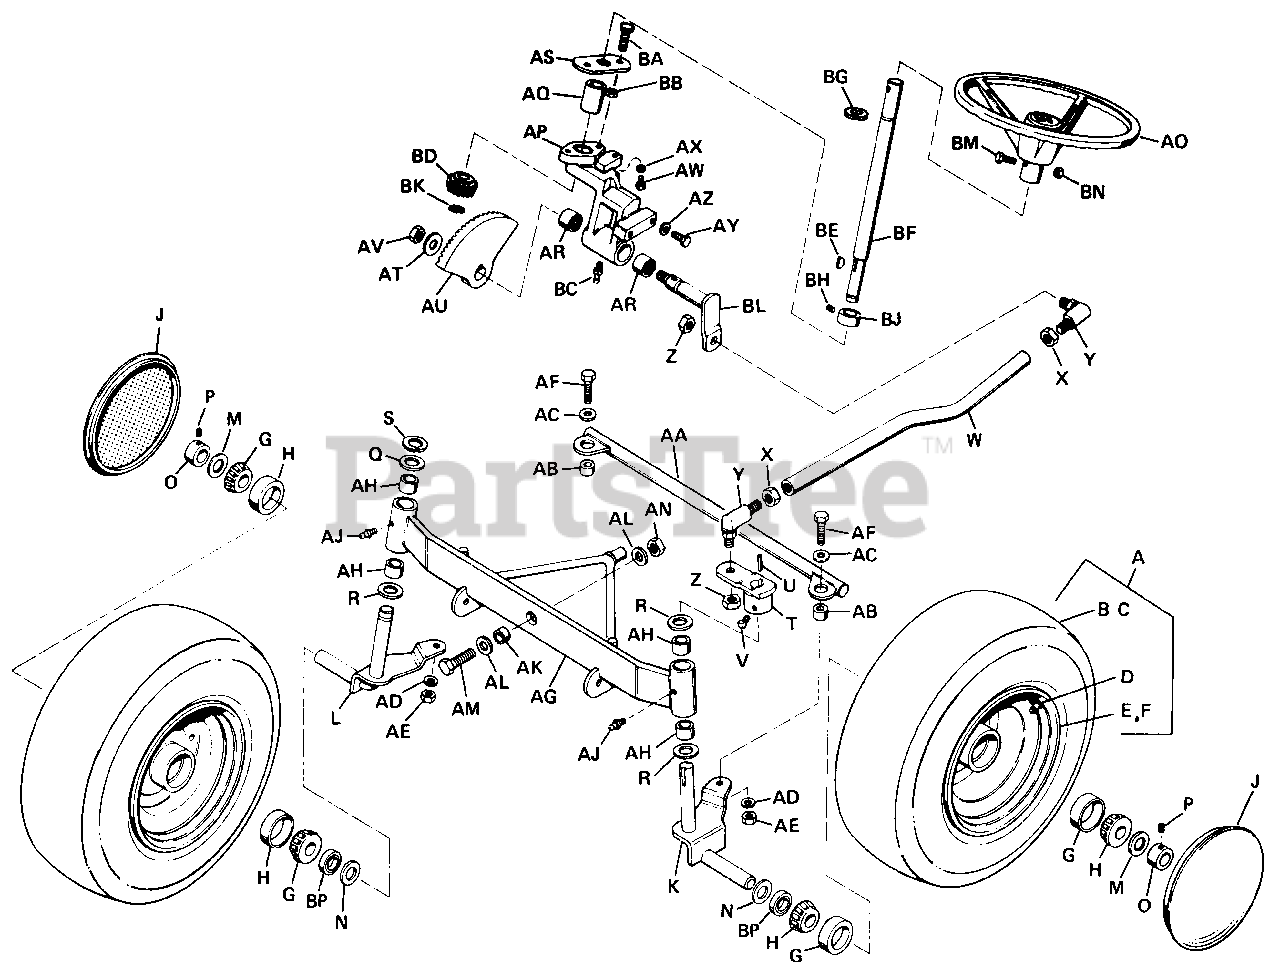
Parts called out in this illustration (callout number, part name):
A	Wheel & Tire Assy. (14 H.P.)
B	Tire (14 H.P.)
C	Tube (14 H.P.)
D	Valve Stem & Cap (14 H.P.)
E	Wheel-Sub Assy. (14 H.P.)
F	Wheel (Front) (14 H.P.)
G	Bearing, Cup
H	Bearing, Cone (Without Seal)
J	Hub Cap
K	Spindle Assy. L.H.
L	Spindle Assy. R.H.
O	Collar, Set
P	Cup Pt. Socket Head Set Screw, 5/16"-18 N.C. x 5/16"
Q	Washer (Use Beneath Snap Ring)
S	Ring, Retaining
T	Arm Assy., Strg. L.H.
V	Cup Pt. Socket Head Set Screw, 5/16"-18 N.C. x 1/2"
X	Hex Nut, Jam, 1/2"-20 N.F.
Y	Joint, Ball
Z	Hex Nut, Jam Lock, 1/2"-20 N.F.
AA	Link Assy., Drag
AC	Washer, Plain, 3/8"
AD	Lock Washer, 3/8"
AE	Hex Nut, Full, 3/8"-16 N.C.
AF	Hex Cap Screw, 3/8"-16 N.C. x 1-1/4"
AG	Axle Assy., Front
AJ	Fitting, Grease
AL	Plain Washer, 1/2"
AM	Hex Cap Screw, 1/2"-13 N.C. x 1-3/4", Grade 5
AN	Hex Nut, Full Lock, 1/2"-13 N.C.
AO	Steering Wheel
AP	Steering Bracket, Casting
AQ	Bushing, Steering
AR	Bearing, Needle
AS	Plate, Steering
AT	Plain Washer, 7/16"
AU	Gear, 23T, Bevel
AV	Hex Nut, Lock, 7/16"-14 N.C.
AW	Hex Cap Screw, 3/8"-16 N.C. x 3/4"
AX	Lock Washer, 3/8"
AY	Hex Cap Screw, 3/8"-16 N.C. x 7/8"
AZ	Lock Washer, 3/8"
BA	Hex Capscrew, 3/8"-16 x 1-1/4"
BB	Hex Jam Nut, 3/8"-16
BC	Fitting, Grease
BD	Pinion, 15T, Bevel
BE	Key, Woodruff, No. 6 5/32" W. x 5/8" Dia.
BF	Shaft, Steering
BG	Ring, Retaining
BH	Set Screw, 5/16"-18 N.C. x 1/4"
BJ	Collar, Set
BK	Ring, Retaining
BL	Arm Assy., Steering
BM	Hex Head Screw, 5/16"-18 N.C. x 1-1/4"
BN	Hex Nut, Lock, 5/16"-18 N.C.
A	Wheel & Tire Assy. (10 H.P.)
B	Tire (10 H.P.)
C	Tube (10 H.P.)
D	Valve Stem & Cap (10 H.P.)
E	Wheel-Sub Assy. (10 H.P.)
F	Wheel (Front)(10 H.P.)
